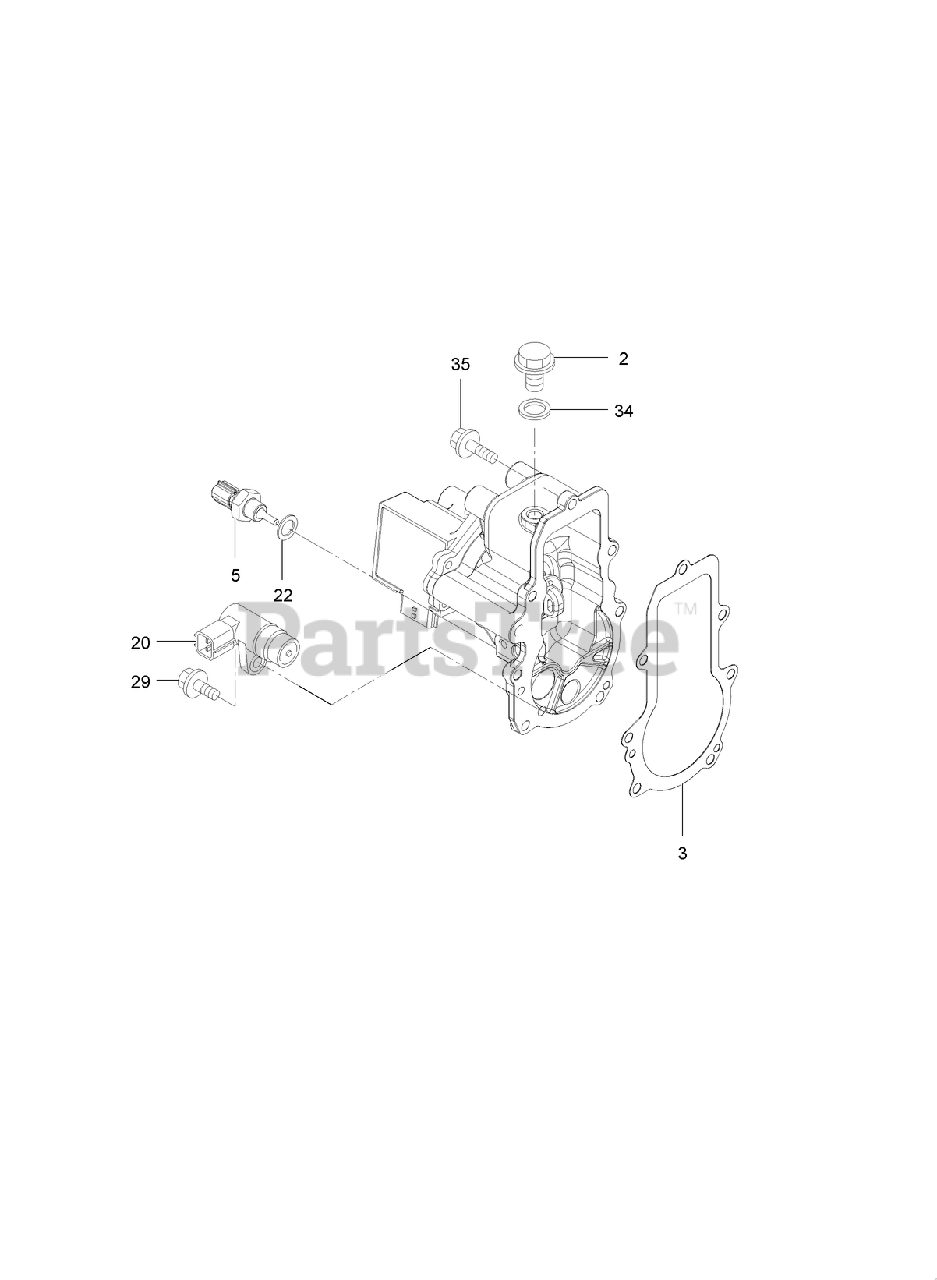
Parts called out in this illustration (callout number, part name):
3	GASKET
5	SENSOR-OIL TEMP
20	SENSOR
22	WASHER-SEAL
34	WASHER-SEAL
